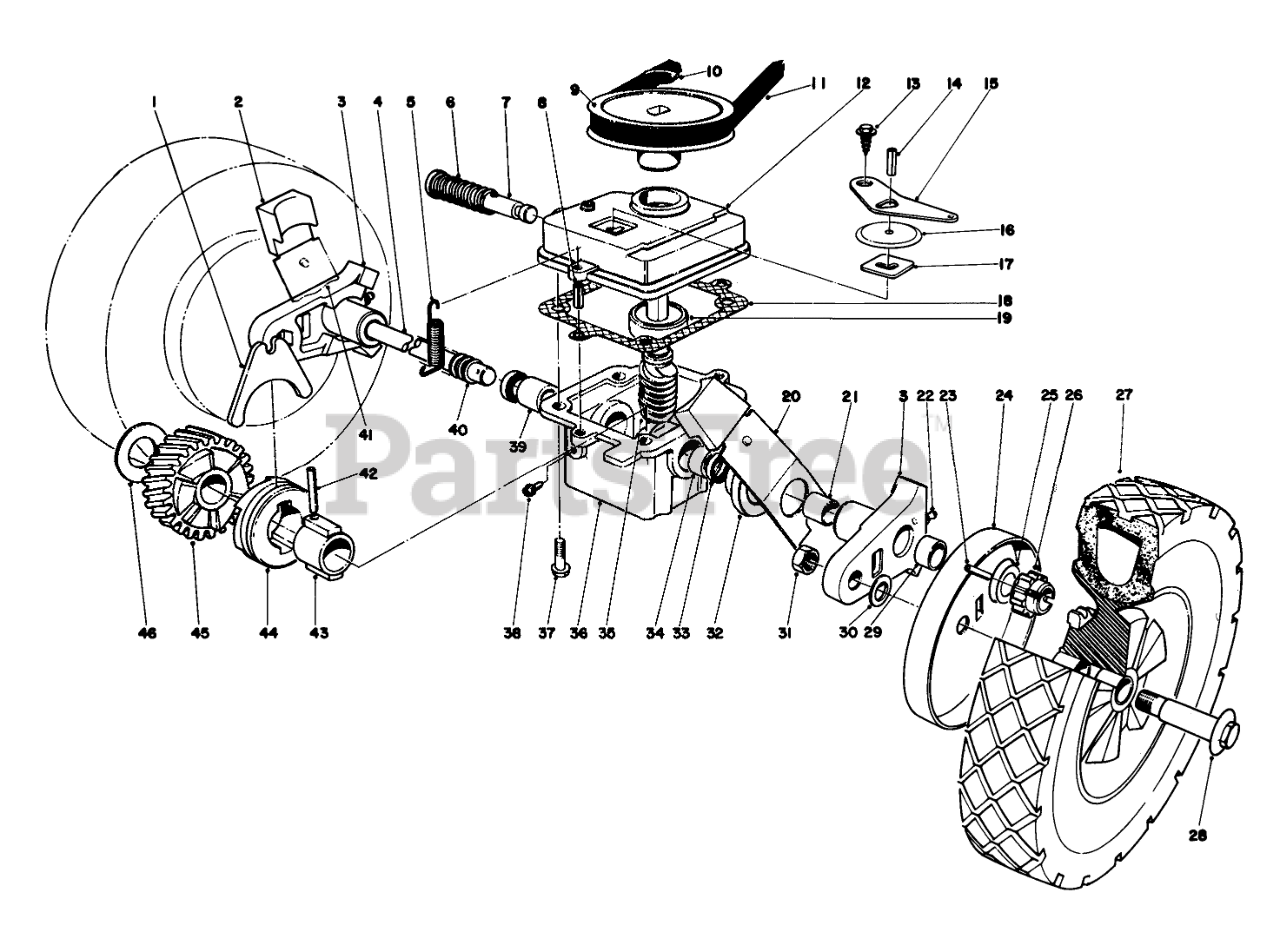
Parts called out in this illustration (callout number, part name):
1	SHIFTER FORK
2	KNOB-ARM
3	Pivot Arm (Incl. Ref. #21, 22 & 29)
4	DRIVE SHAFT (SERVCE)
5	TENSION SPRING
6	SPRING
7	Shift Rod
8	3/16 X 1/2 ROLL PIN
9	PULLEY
10	PUSH-ON 93-3236
11	V BELT
12	Cover Gear Case
13	Screw
14	PIN-ROLL
15	SHIFTER ARM
16	TRANS DUST COVER
17	LATCH PLATE
18	GASKET
19	Bearing
20	SPRING ARM ASM SP LH
21	BUSHING
22	FITTING-GREASE
23	Pin
24	WHEEL COVER
25	WASHER-THRUST
26	Pinion
27	Wheel & Tire Assembly
28	BOLT-WHEEL
29	BUSHING
30	WASHER
31	Nut
32	End Cap
33	Seal
34	Bushing
35	Worm Shaft & Gear (Incl.Ref. #45)
36	Gear Case (Incl.Ref. #33, 34 & 39)
37	Screw
38	NYLON SCREW
39	Bushing
40	COVER-SHAFT, DRIVE
41	SPRING ARM ASM SP RH
42	COIL PIN
43	SLEEVE
44	CLUTCH JAW
45	Helical Gear
46	THRUST WASHER
